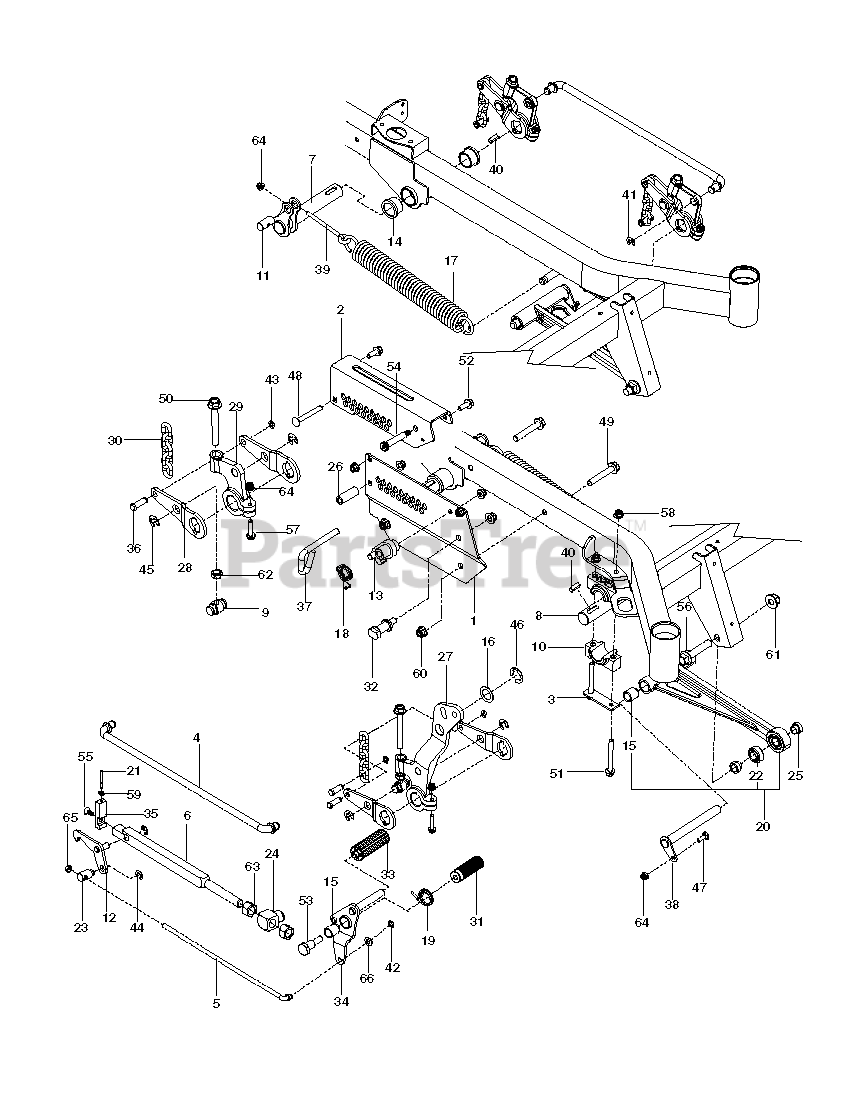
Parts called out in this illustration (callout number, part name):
1	PLATE, INNER HEIGHT, BLUE
3	PLATE, PILLOW BLACK
4	ROD, LIFT
5	ROD, HEIGHT LATCH
6	BAR, HEIGHT
7	SHAFT, RR LIFT
8	SHAFT, LIFT, FT
9	SHAFT, LIFT TRUNION
10	BLOCK, PILLOW
11	PIVOT, SPRING
12	LATCH, HEIGHT WLDMT
13	LATCH, TRANSPORT WLDMT
14	BUSHING, FLANGE 1.25 X 1.0
15	BUSHING, SLEEVE 3/4 X 1.0
16	MACHINE BUSHING
17	SPRING, EXTENSION
18	SPRING, TORSION
19	SPRING, TORSION
20	ASSEMBLY, STRUT
21	LINK, INDICATOR
22	BALL JOINT, 3/4" SWIVEL
23	SWIVEL, HEIGHT LATCH
24	SWIVEL, HEIGHT BAR
25	SPACER, STRUT
26	SPACER, HEIGHT PLATE
30	LIFT CHAIN
31	PAD, FOOT PEDAL
32	GUIDE, HEIGHT BAR
33	PEDAL, DECK HEIGHT
34	PEDAL, RELEASE WLDMT
35	CAP, HEIGHT BAR
36	PIN, 7/16 CLEVIS
37	PIN, HEIGHT
38	PIN, STRUT
39	EYE BOLT 4.5`
40	KEY, 5/16 SQ X 1.0
41	5/8 E-RING
42	E RING 3/8"
43	RING, E, 7/16
44	E-RING 1/2
45	E RING 3/4
46	E-RING 1"
47	RHSNB 5/16C X 1
48	3/8-16 X 3` CARR BOLT
49	HFFS 1/2-13 X 3 GD 5 ZD
50	HHFS 1/2-13 X 4 GR 5
51	HHFS 3/8-16 X 3.5 GD 5 ZD
52	HHFS 3/8-16 X 1 GRD 5 ZD
53	BOLT, SHOULDER
54	BOLT, SHOULDER, 1/2 X 2.25
55	SCREW, 5/16-18 X 3/4 FLAT HEX
56	HHFS 5/8-11 X 3.0 GD 8 ZD
57	HHFS 5/16-18 X 1.5 GD 5
58	NUT 3/8-16 HEX FLG NYLOC ZD
59	NUT 1/4-20 JAM
60	NUT, 1/2-13 HEX FLG NYLOC ZD
61	NUT 5/8-11 FLG NYLOC ZD
62	NUT 1/2 HEX JAM
64	5/16-18 NYLOC FLANGE NUT
65	NUT 3/8-24 JAM
66	WASHER 3/8 SAE FLAT
